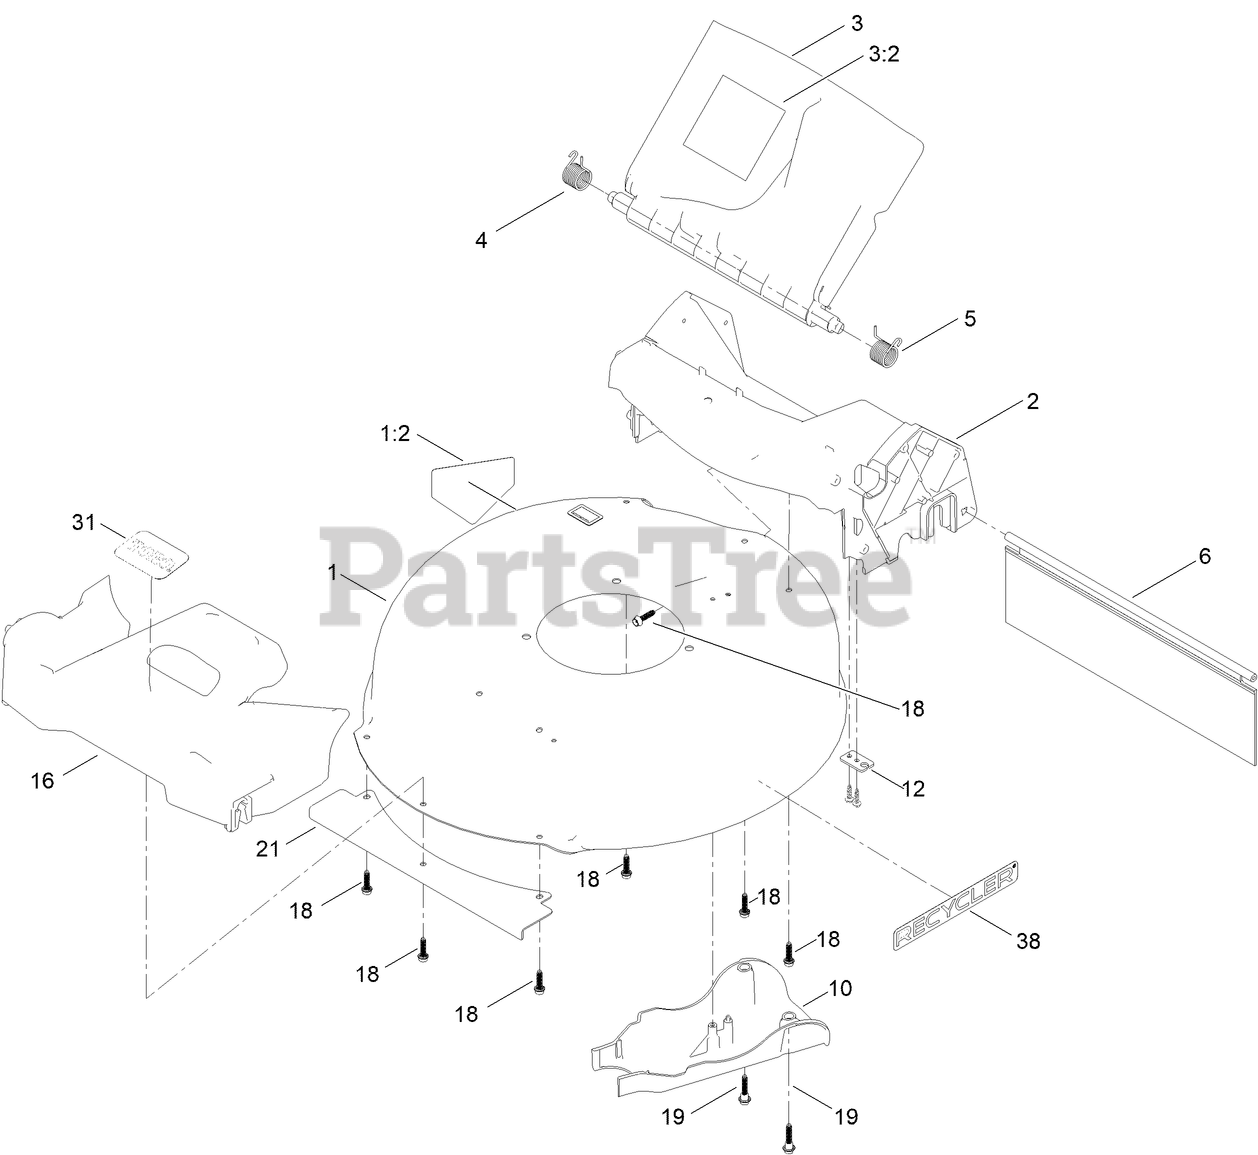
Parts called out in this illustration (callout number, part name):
1	HOUSING-DECK
1:2	DECAL-DANGER
2	CHUTE-SP/AWD, 21 IN
3	DEFLECTOR-REAR ASM
3:2	DECAL-WARNING
4	SPRING-TORSION
5	SPRING-TORSION
6	SHIELD-TRAILING
10	COVER-BELT
12	BRACKET-CABLE
16	BUMPER
18	SCREW-FLANGE, PLASTIC
19	SCREW-SHOULDER, HHF
21	SHIELD-FRONT
31	DECAL-TORO, SILVER
